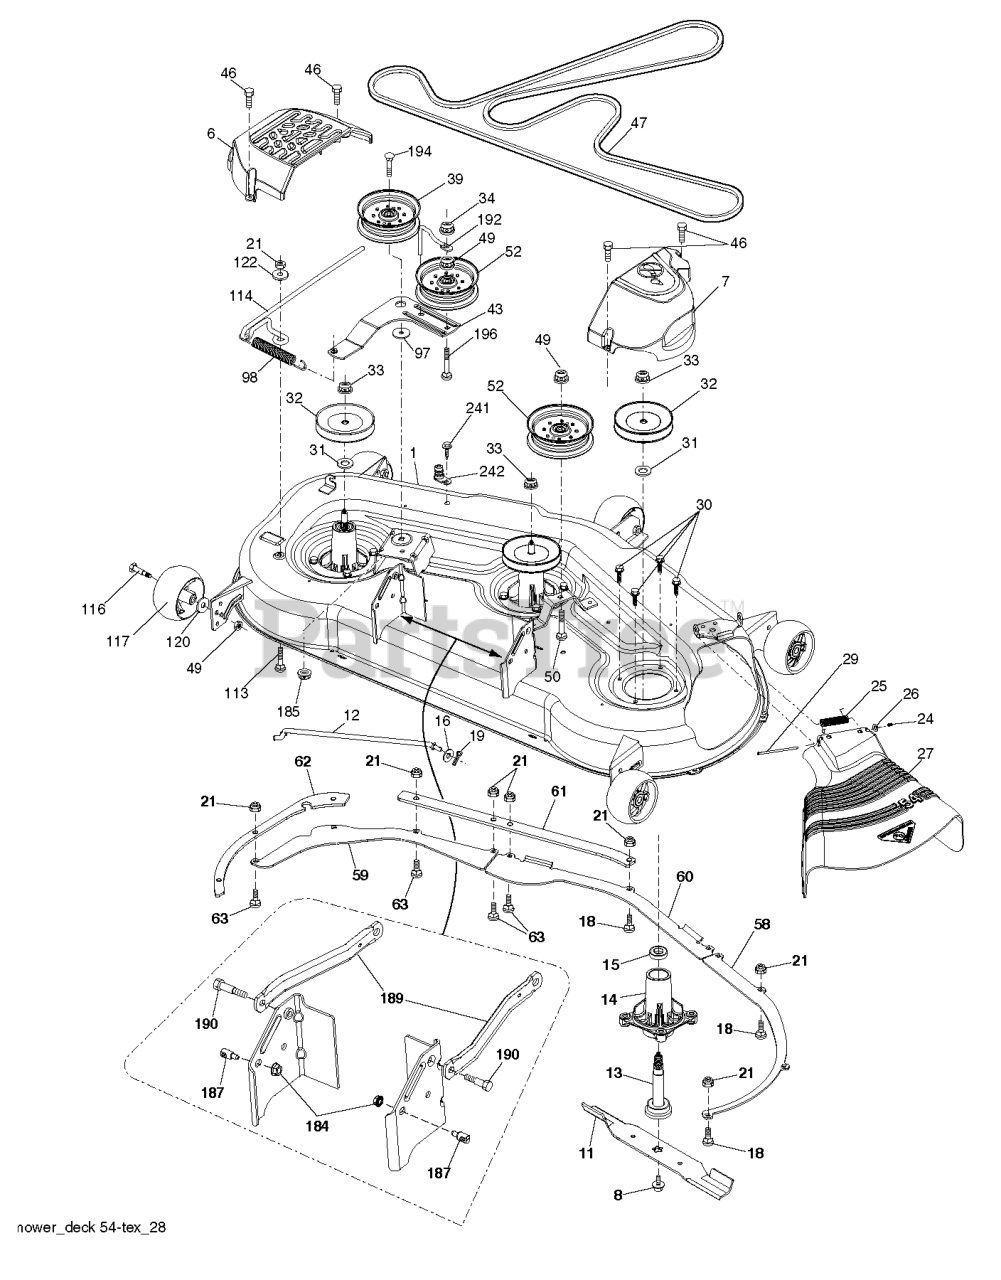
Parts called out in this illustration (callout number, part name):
1	DECK.WLDMT.W/TUBES.54".ORANGE
6	COVER.MANDREL.LH.54"20
7	COVER.MANDREL.RH.54.20
8	BOLT.WASHER.ASM.7/16-2
11	BLADE.BAGGING.54"
12	ROD.ANTI.SWAY.48/54"K4
13	SHAFT ASM MANDREL
14	RP.HOUSING.MANDREL.4PT.
16	WASHER
18	BOLT
19	PIN.COTTER.5/16.BOW TI
21	LOCKNUT
24	CAP-SLEEVE LT
25	SPRING, TORSION
26	NUT PUSH M
27	DEFLECTOR
29	ROD.HINGE
30	SCREW, WASHER HEAD
31	WASHER.SPACER.MANDREL
32	PULLEY/MANDREL
33	NUT.FLANGE.LOCK.TOP
39	RB PULLEY.IDLER.4.50/HUB SPEC
43	ARM.IDLER
46	SCREW.1/4-20X5/8
47	RP.BELT.DRIVE.54."2006
49	NUT LOCK FLG 3/8-16 UNC
50	BOLT
52	PULLEY.IDLER.2006
58	BAFFLE.RIGHT.54"
59	BAFFLE.LEFT.54"
60	BAFFLE CENTER 54" MOWER
61	PLATE.REIN.FRONT.BOLT54"X431
62	PLATE.REIN.SIDE.BOLT.54"X431
63	BOLT.CARRIAGE.5/16-18
98	SPRING, DECK DRIVE
113	BOLT CRT
114	ROD TENSION RELIEF
116	BOLT.SHOULDER.3/8-16X3-5/8.
117	RP WHEEL. GUAGE RALLY
120	WASHER
122	BUSHING.RELIEF.TENSION
184	NUT LOCK HEX FLANGE 5/16-18
185	NUT.LOCK.FLANGE.7/16
187	STUD.FASTNER.W/ANTI-ROTATE
189	ARM.SUSPENSION.MOWER
190	BOLT.SHOULDER
192	KEEPER.BELT.IDLER.54"T
194	BOLT.HEX.WASHER.HEAD.7/16-24X
196	BOLT
241	SCREW.TT.#10-32X.5.3/8.FLANGE
242	PORT.WASHOUT
